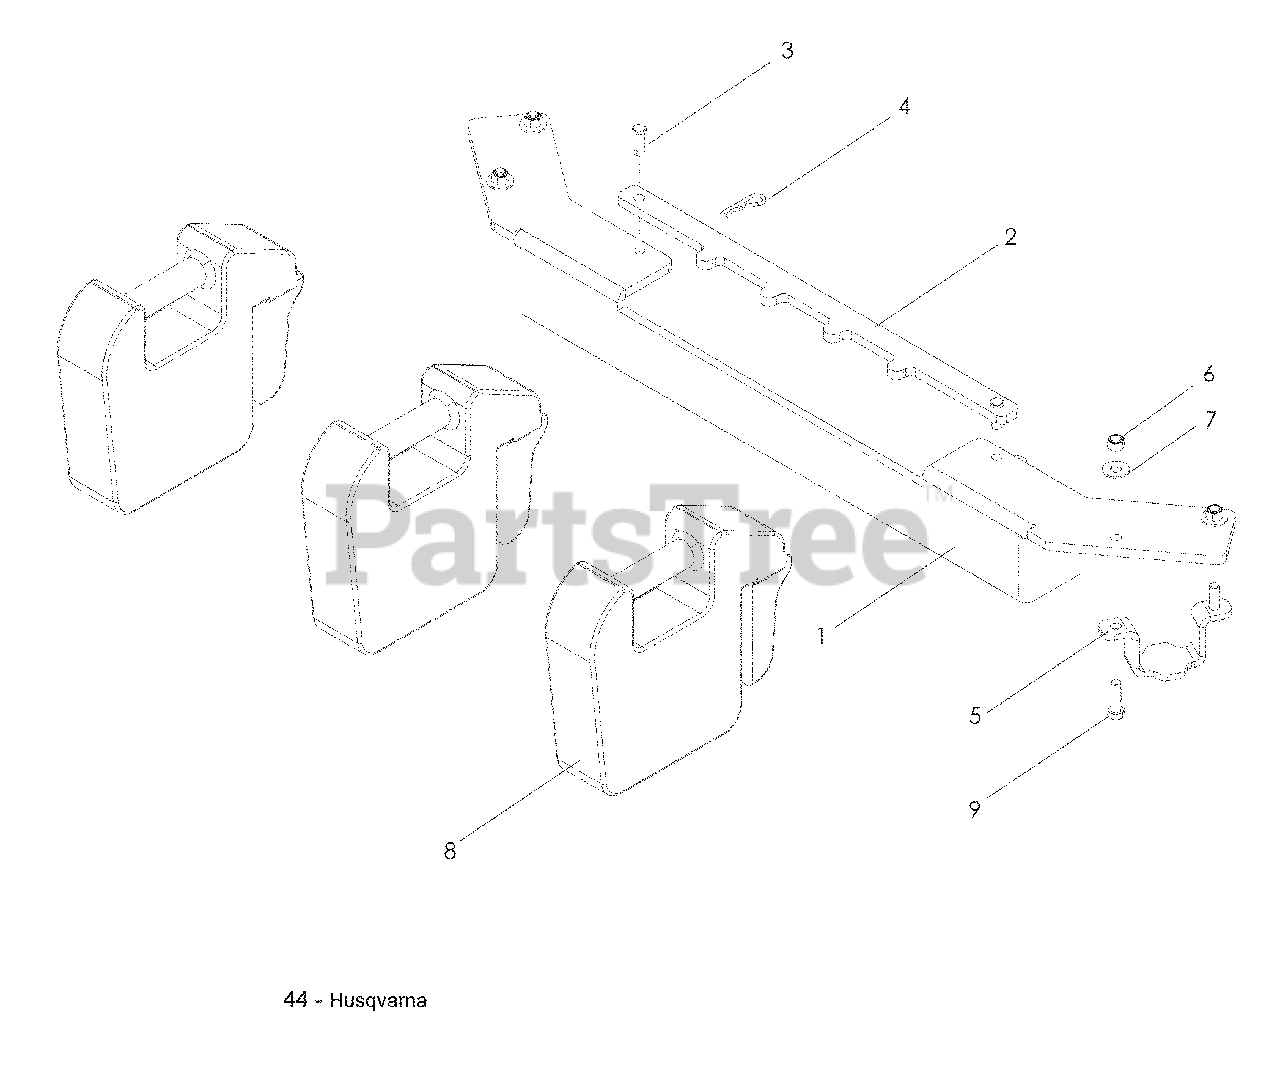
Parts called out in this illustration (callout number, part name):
1	WEIGHT BAR, FRONT
2	HOLD DOWN, WEIGHT BAR
3	CLEVIS PIN
4	SPRING RETAINER
5	WEIGHT KEEPER
6	NUT 3/8-16 HEX NYLOC
7	WASHER 3/8 STD FLT
8	CAST COUNTERWEIGHT
9	HCS 3/8-16 x 1¼
